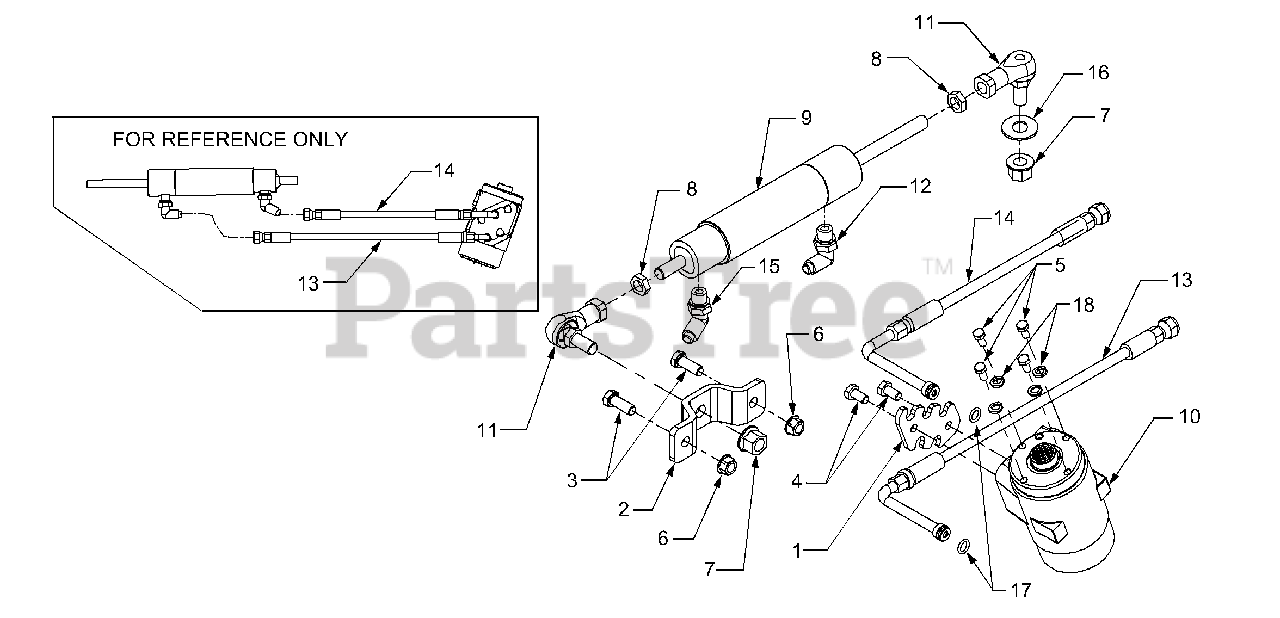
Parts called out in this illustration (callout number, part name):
1	Plate, Steering Pump Port
2	Bracket, Cylinder Mounting
3	Screw, Hex Cap 3/8-16 x 1.0 GR5
4	Screw, Hex Cap M8-1.25 x 16MM GR5
5	Screw, Hex Cap, M6 x 14MM
6	Nut, Hex Flange Lock, 3/8-16
7	Nut, Hex Flange Lock, M12 x 1.75
8	Nut, Hex, M12 x 1.75 RH
9	Cylinder, Steering
10	Pump, Hydraulic Steering
11	Ball Joint, 12MM x 1.75 RH
12	Fitting, 90 Degree Elbow
13	Hose, Front Steering
14	Hose, Rear Steering
15	Fitting, 45 Degree
16	Washer, Flat, .51 x 1.12 x .060
17	O-Ring, .426 x .566 x .070
18	Washer, Lock, 1/4"
